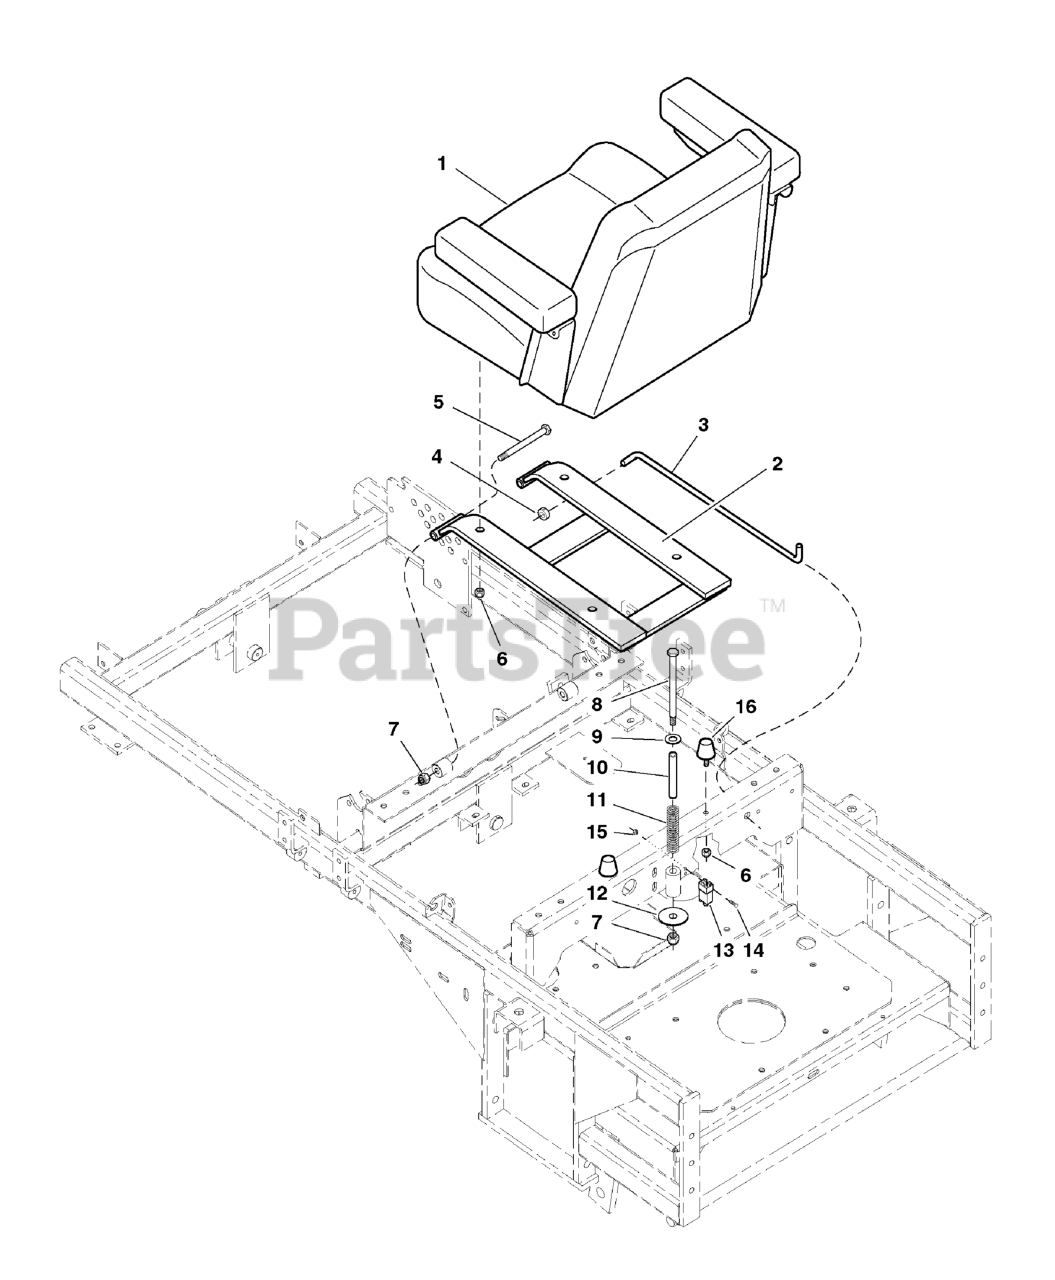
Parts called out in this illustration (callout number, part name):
1	SEAT, GRAY, NO LOGO, CMPT
1	CUSHION, Seat, Gray
1	CUSHION, BACK
1	ARM REST, Black
2	SEAT MOUNT
3	SEAT STOP ROD
4	COLLAR, 5/16" Set
5	BOLT, 3/8-16 X 4" GD5 CZ
6	NUT, 5/16-18 Hex Nylon Lock
7	NUT, 3/8-16 HEX NYLON LOCK
8	BOLT, 3/8-16 X 6" GD5 CZ
9	WASHER, 3/8 SAE
10	SPACER, .38 x .50 x 5.06
11	SPRING, Compression
12	WASHER, 3/8 x 2
13	SWITCH, PLUNGER, N.O./N.C.
14	SCREW, #10-24 X 1 RS, CZ
15	NUT, #10-24 Hex
16	RUBBER BUMPER
17	SPRING, EXTENSION, SEAT ADJUSTMENT (YEL OR BLK)
